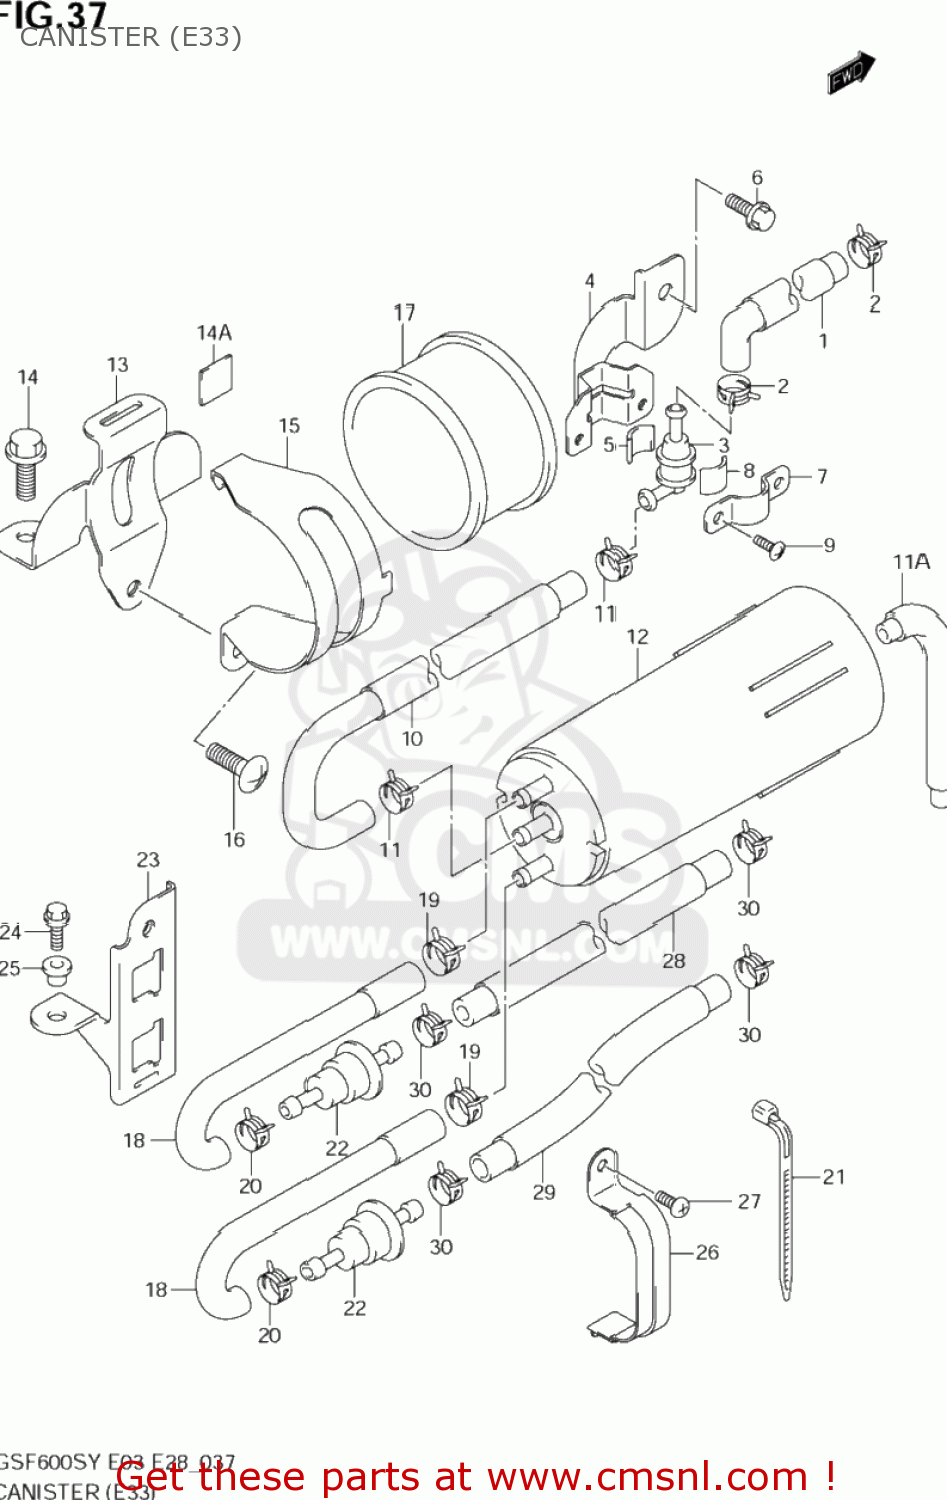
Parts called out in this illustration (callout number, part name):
1	HOSE TANK & BREATHER VALVE
2	CLIP
3	VALVE,FUEL TANK BREATHER
4	BRACKET,FUEL TANK BREATHER
5	CUSHION
6	BOLT
7	PLATE,FUEL TANK BREATHER NO.2
8	CUSHION
9	SCREW
10	HOSE,CSTR & BREATHER VALVE
11	CLIP
11A	HOSE,DRAIN
12	CANISTER ASSY,CHARCOAL
13	BRACKET,CANISTER
14	BOLT
14A	CUSHION,BRACKET
15	HOLDER,CANISTER
16	SCREW 6X12
17	CUSHION,CANISTER
18	HOSE,CSTR & PURGE VALVE
19	CLIP
20	CLIP
21	CLAMP(L:165)
22	VALVE,CANISTER PURGE
23	BRACKET,CANISTER PURGE VALVE
24	BOLT
25	WASHER (5X14X1)
26	HOLDER,CANISTER PURGE
27	SCREW
28	HOSE,CARB & PURGE VALVE
29	HOSE,CARBURETOR & PURGE VALVE
30	CLIP
